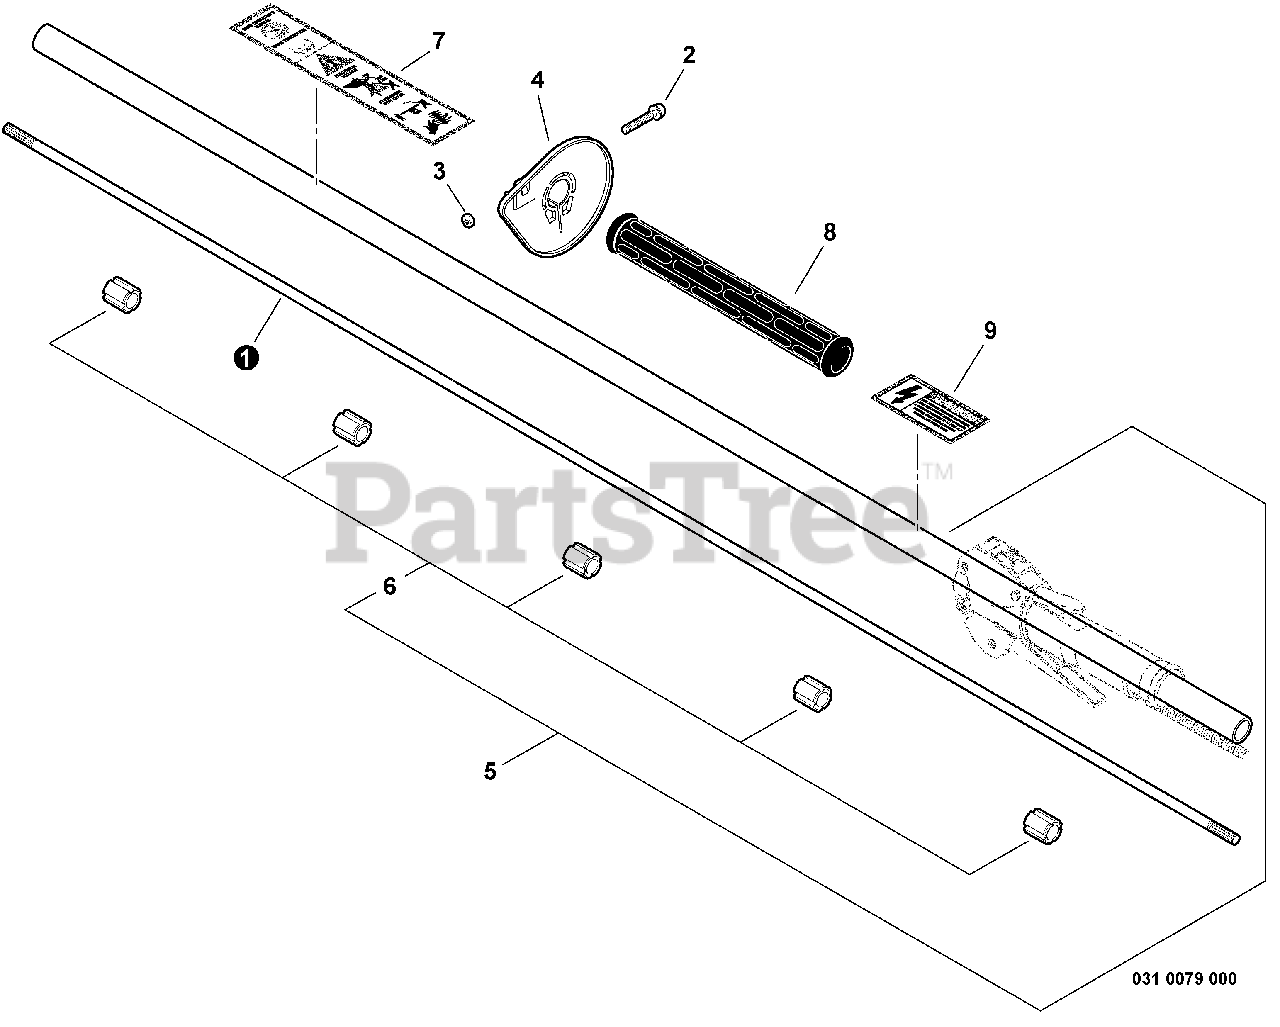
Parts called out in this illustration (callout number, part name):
1	DRIVESHAFT - SOLID
2	SCREW - 5X30
5	MAIN PIPE ASSY
6	BUSHING
7	LABEL - CAUTION
8	GRIP - FRONT
9	LABEL - DANGER
